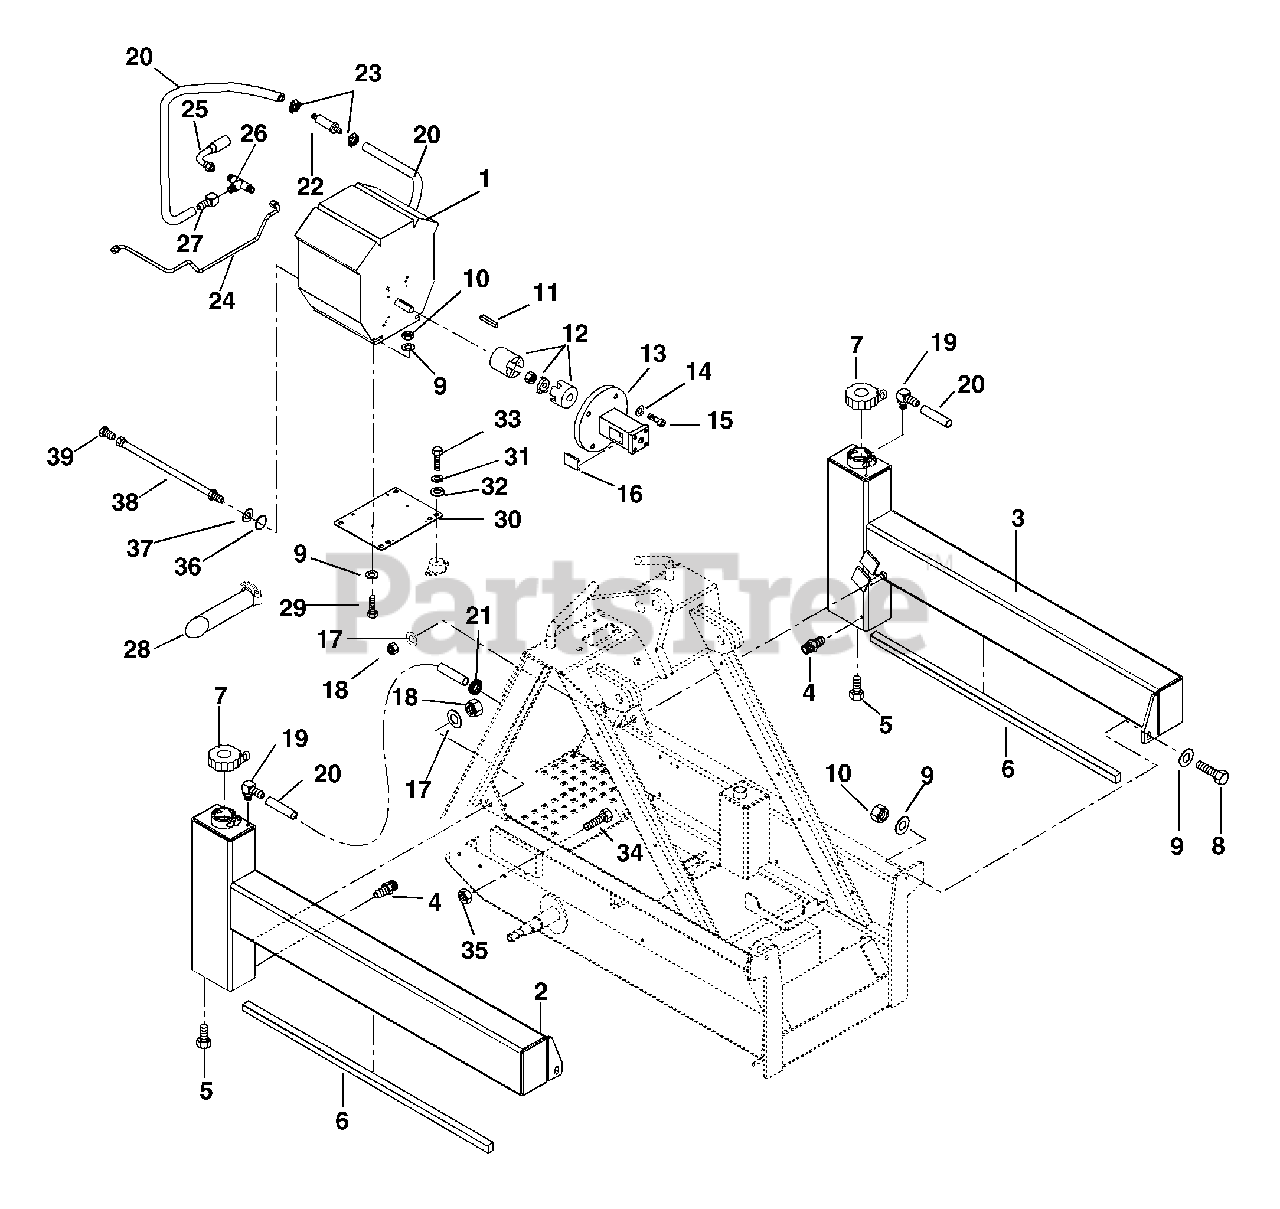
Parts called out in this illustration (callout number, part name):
1	Engine-Honda
2	Tank-Fuel Gas Right Hand
3	Tank-Fuel Gas Left Hand
4	Adapter-Male Connector .438-20 x .125-27
5	Plug-Pipe .125-27 NPT
6	Gasket-Foam with Adhesive Back
7	Cap-Fuel Tank
8	Bolt-Hex M10-1.5 x 40
9	Washer-Flat-Steel .406 x .812 x .065
10	Nut-Locking-Nylon M10-1.5
11	Key-Square .25 x 1.25 x .25 SAE
12	Coupling
13	Bell-Housing
14	Washer-Locking .44 .109
15	Bolt-Hex .44-14 x 1.50 Grade 5
16	Cover-Access
17	Washer-Flat-Steel .531 x 1.06 x .095
18	Nut-Locking-Nylon M12-1.75
19	Fitting-Barber 90 Degree Elbow .125-27 NPT x .25 I.D. Hose
20	Line-Gas
22	Filter-Fuel
23	Clamp-Hose
24	Tube-Fuel Line-Long
25	Tube-Fuel Line-Short
26	Adapter-Tee .56-18
27	Fitting-Hose .375-M6
28	Extension-Muffler Exhaust
29	Bolt-Hex M10-1.5 x 45
30	Mount-Engine Plate
31	Washer-Locking .50 x .125
32	Washer-Flat-Steel .531 x 1.06 x .095
33	Bolt-Hex .50-20 x 1.00 Grade 5
34	Bolt-Hex M6-1.0 x 25
35	Nut-Locking-Nylon M6-1
36	O-Ring M14 x 1.5
37	Ring, Retaining M14
38	Hose, Engine Oil Drain
39	Plug .44-20
